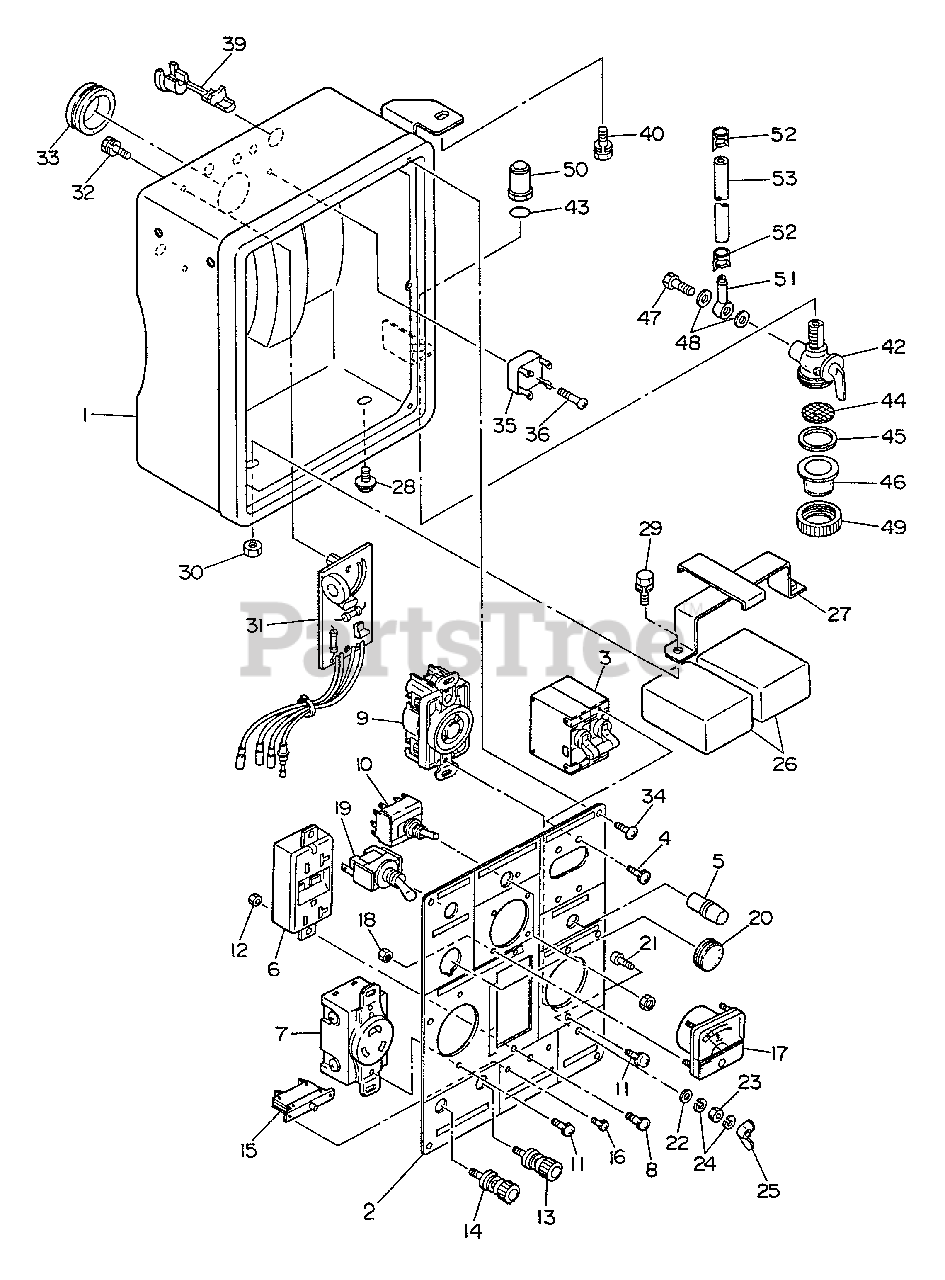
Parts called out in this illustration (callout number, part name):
1	CONTROL BOX ASSY
2	CONTROL PANEL ASSY
3	CIRCUIT BREAKER (250V-14A)
4	SCREW
5	LAMP, NEON
6	AC RECEPTACLE - 125V-20A, GFCI
7	AC RECEPTACLE - 125/250V-20A
8	SCREW
9	AC RECEPTACLE - 125/250V-20A
11	SCREW
12	NUT
13	BOLT, TERMINAL - RED
14	BOLT, TERMINAL - BLACK
15	CIRCUIT BREAKER - 10A DC
16	SCREW
17	AC VOLT METER
18	NUT
19	SWITCH ASSY
20	GROMMET
21	SCREW
22	WASHER
23	NUT
24	WASHER, SPRING
25	WINGNUT
26	CONDENSER
27	CONDENSER BRACKET ASSY
28	BOLT, FLANGE
29	BOLT
30	NUT
31	IDLE CONTROL UNIT
32	SCREW
33	GROMMET
34	SCREW - TAPPING
35	DIODE STACK ASS'Y
36	SCREW - TAPPING
39	CORD BUSH
40	BOLT
42	FILTER, FUEL
43	O-RING
47	BOLT, BANJO
48	FIBER PACKING
49	NUT, LOCK
50	CLAMP, HOSE
51	BOLT, BANJO
52	CLAMP, HOSE
53	RUBBER PIPE (6×12×160 MM)
